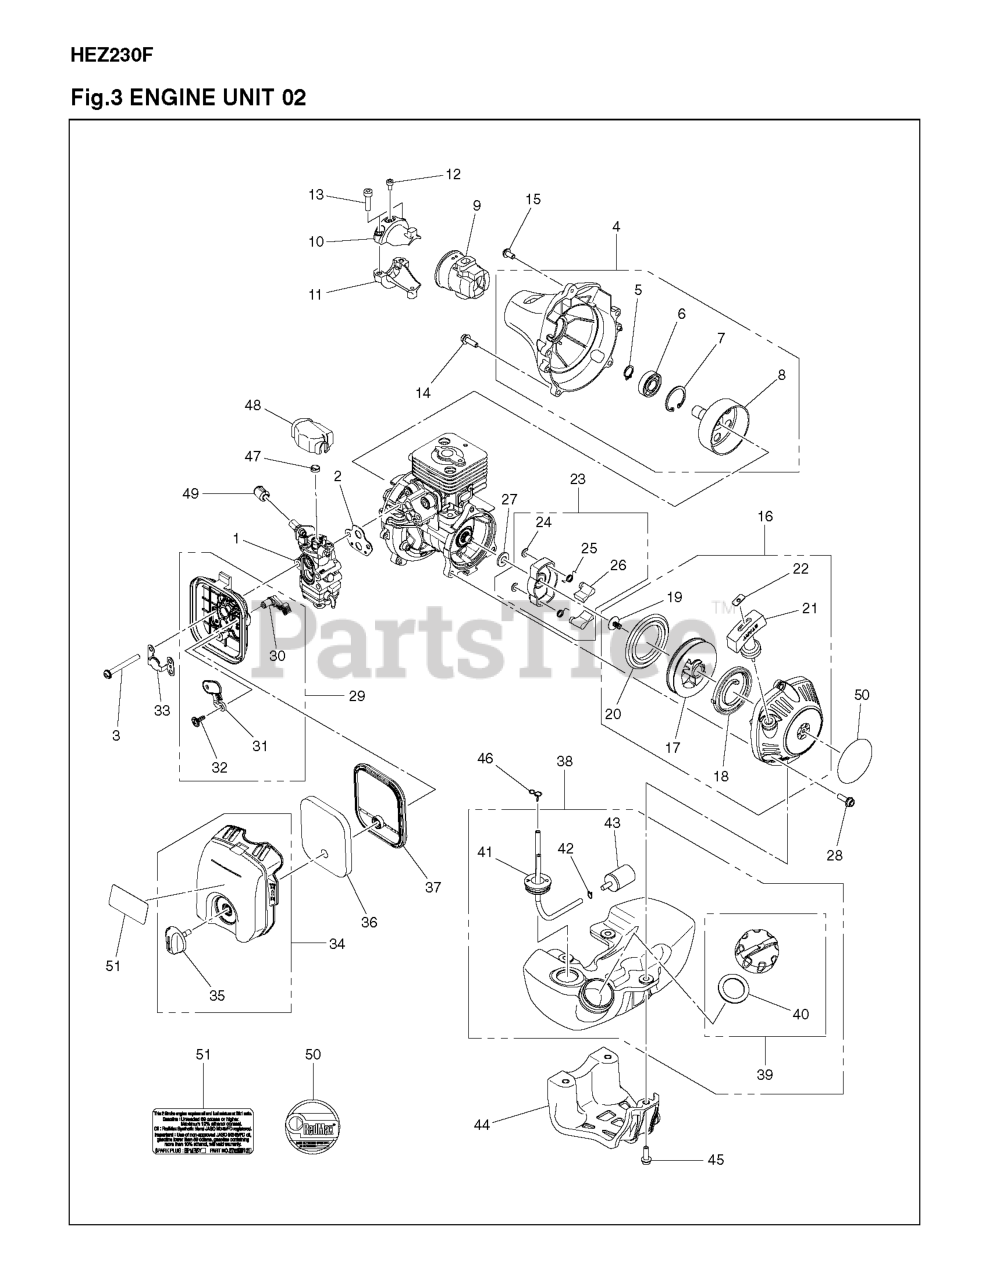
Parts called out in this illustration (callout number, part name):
1	CARBURETOR ASSY
2	GASKET CARBURETOR
4	CLUTCH COVER
8	CLUTCH DRUM
9	CUSHION UPPER
10	BRACKET UPPER M5X0.8
11	BRACKET LOWER
13	BOLT M5X20 T27
14	BOLT M5 X 16
16	STARTER ASSY
17	STARTER PULLEY
18	SPRING, SPIRAL
19	SCREW
20	ROPE
23	STARTER PULLEY ASSY
27	WASHER T2.0MM
28	BOLT TORX 8488151600
29	FILTER HOUSING ASSY
31	PLATE
34	COVER ASSY
35	Cleaner Knob
36	AIR FILTER
38	ASSY TANK EVAP
39	TANK CAP
41	PIPE ASSY
42	CLIP
43	FUEL FILTER
44	SKID PLATE
45	BOLT M5X25
46	CLIP
50	DECAL STARTER
51	DECAL , GASOLINE
